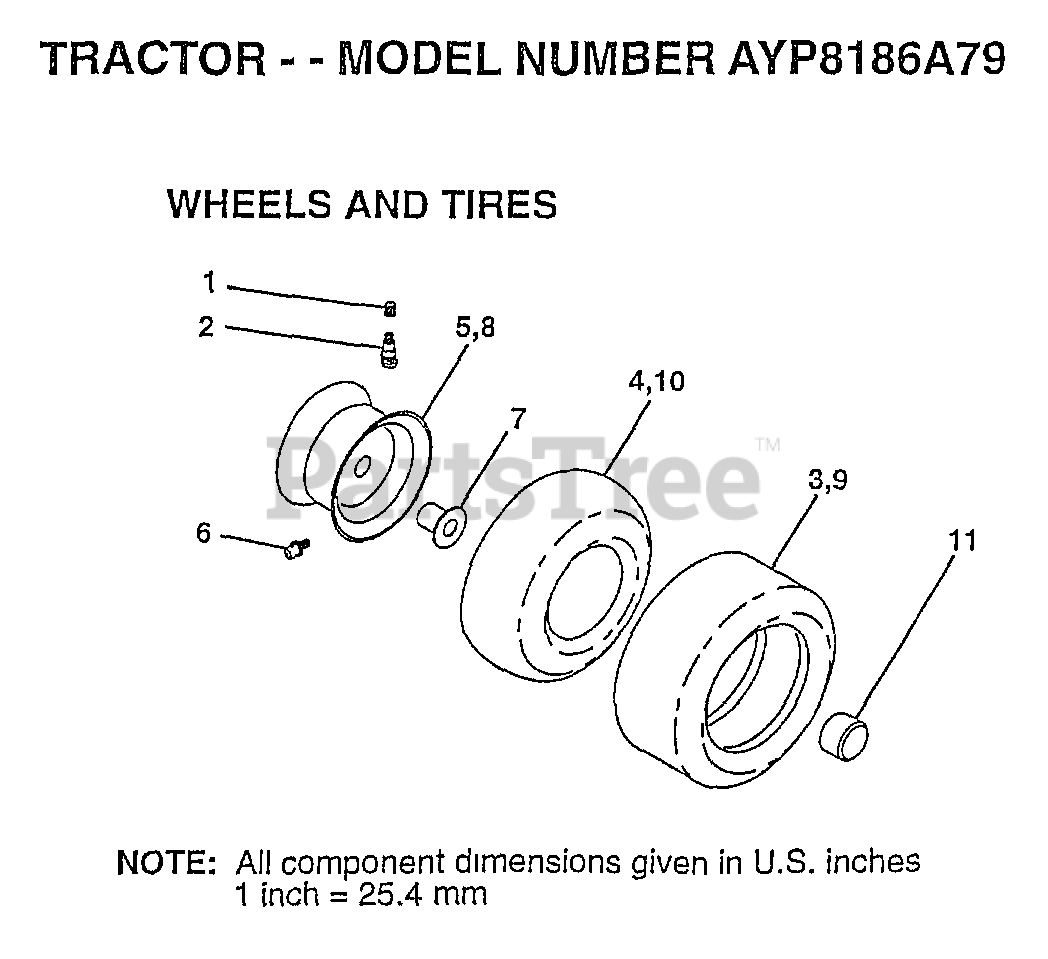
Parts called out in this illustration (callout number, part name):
1	VALVE CAP
2	VALVE STEM LT
4	TUBE.5.3/4.5/6
5	"RIM ASM 8"" FRT"
6	FITTING LT
7	"FLANGE, BEARING"
8	RIM.REAR.
10	TUBE.23X8/10-12
11	HUB CAP
